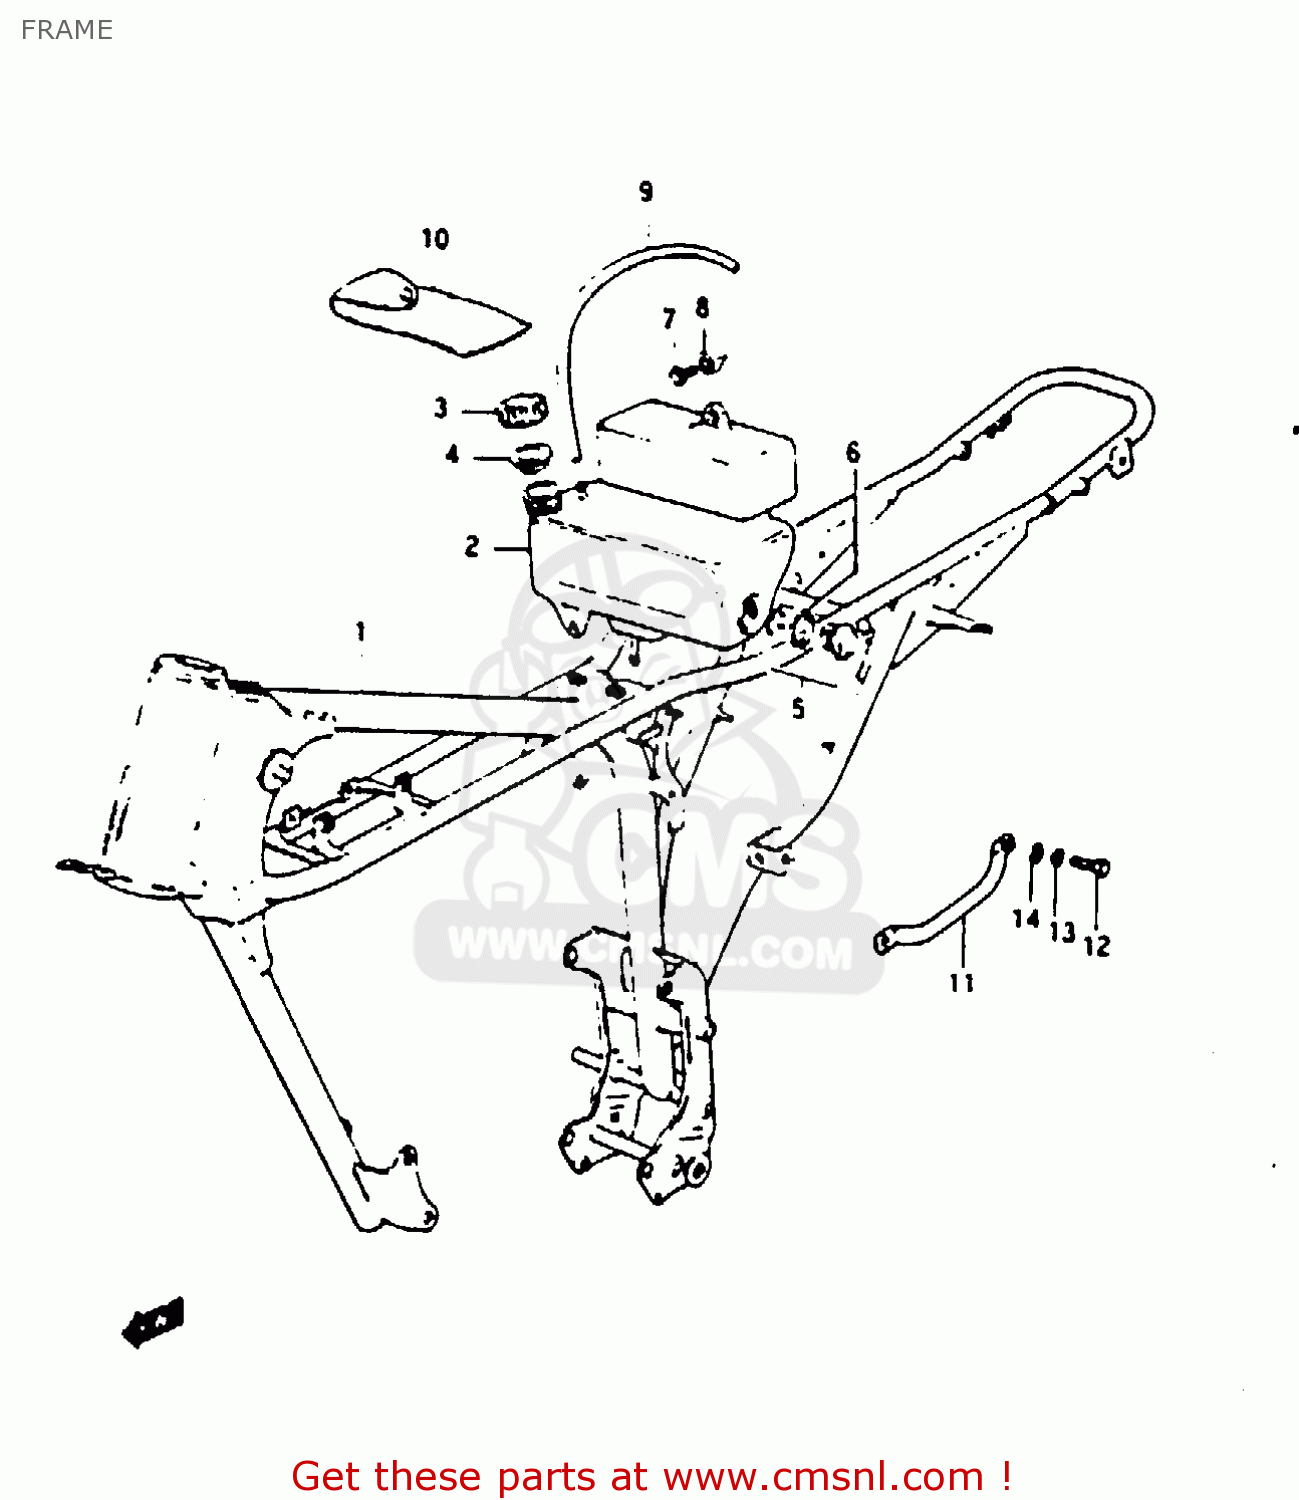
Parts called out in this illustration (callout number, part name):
1	FRAME (BLACK)
2	TANK,OIL
3	CAP,OIL TANK
4	GASKET,OIL TANK CAP (NAS)
5	LENS SET,OIL LEVEL
6	GASKET (NAS)
7	BOLT
8	WASHER
9	HOSE
10	TOOL ASSY
11	GRIP, FRAME HANDLE
12	BOLT 8X12
13	LOCK WASHER
14	WASHER
